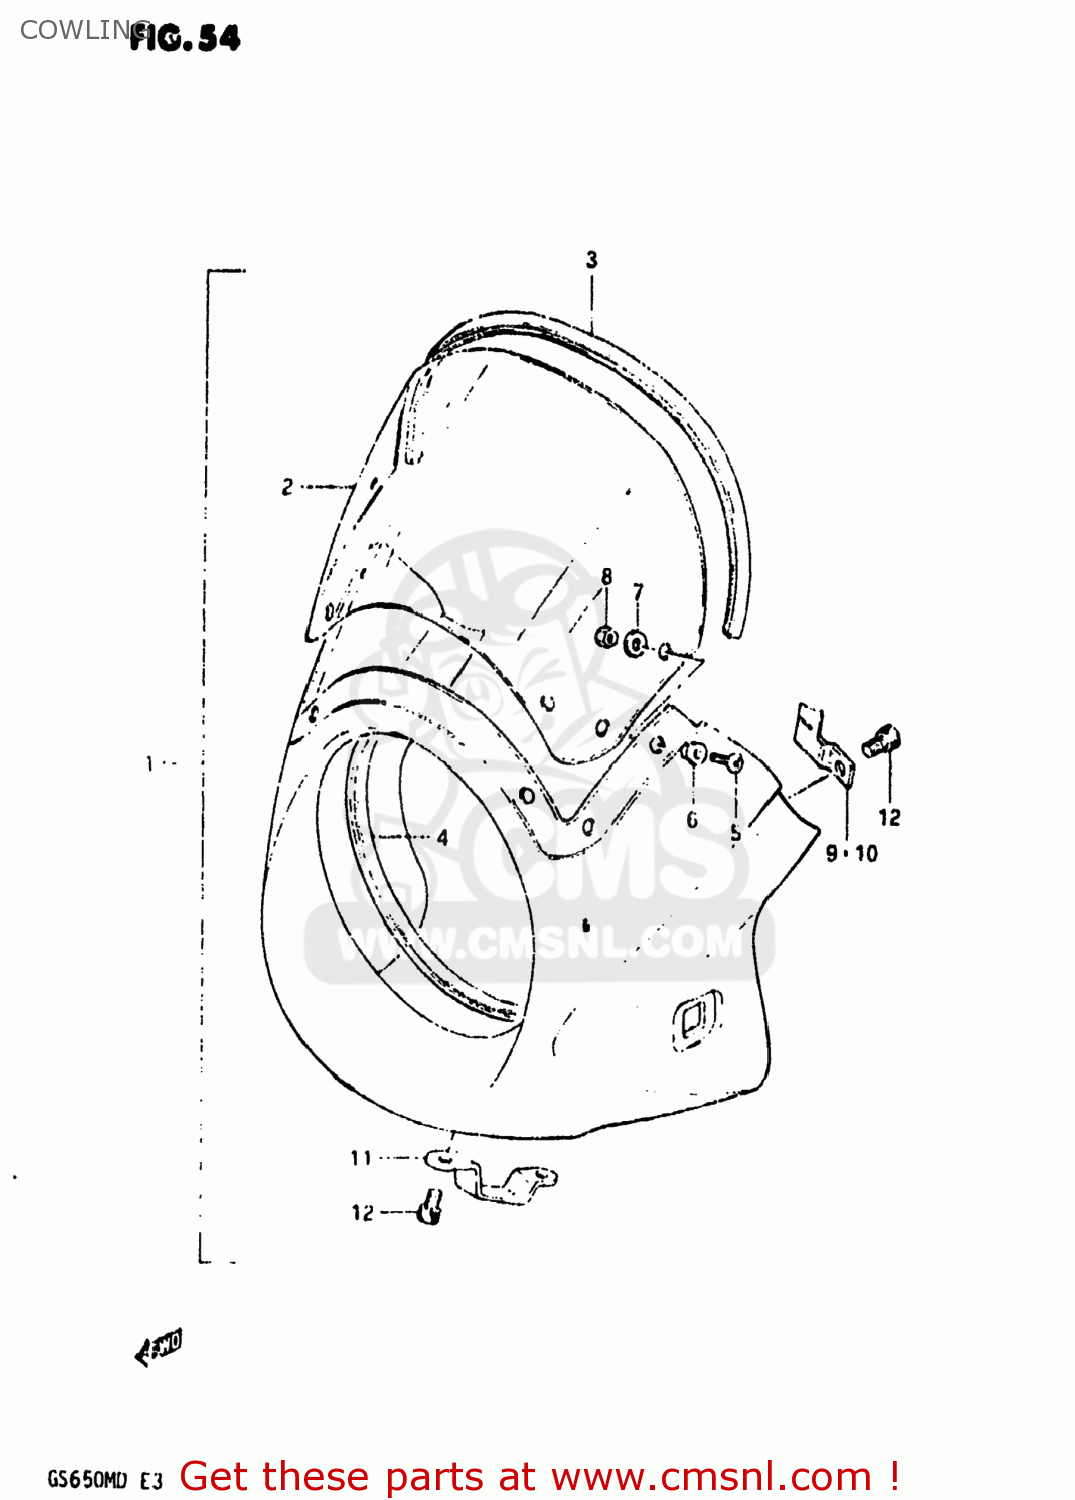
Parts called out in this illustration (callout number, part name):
1	COWLING ASSEMBLY,BODY
2	WINDSCREEN
3	MOLDING
4	MOLDING,COWLING
5	SCREW(5X12)
6	CUSHION
7	WASHER
8	NUT
9	BRACKET,COWLING,RIGHT
10	BRACKET, LH
11	BRACKET
12	BOLT
